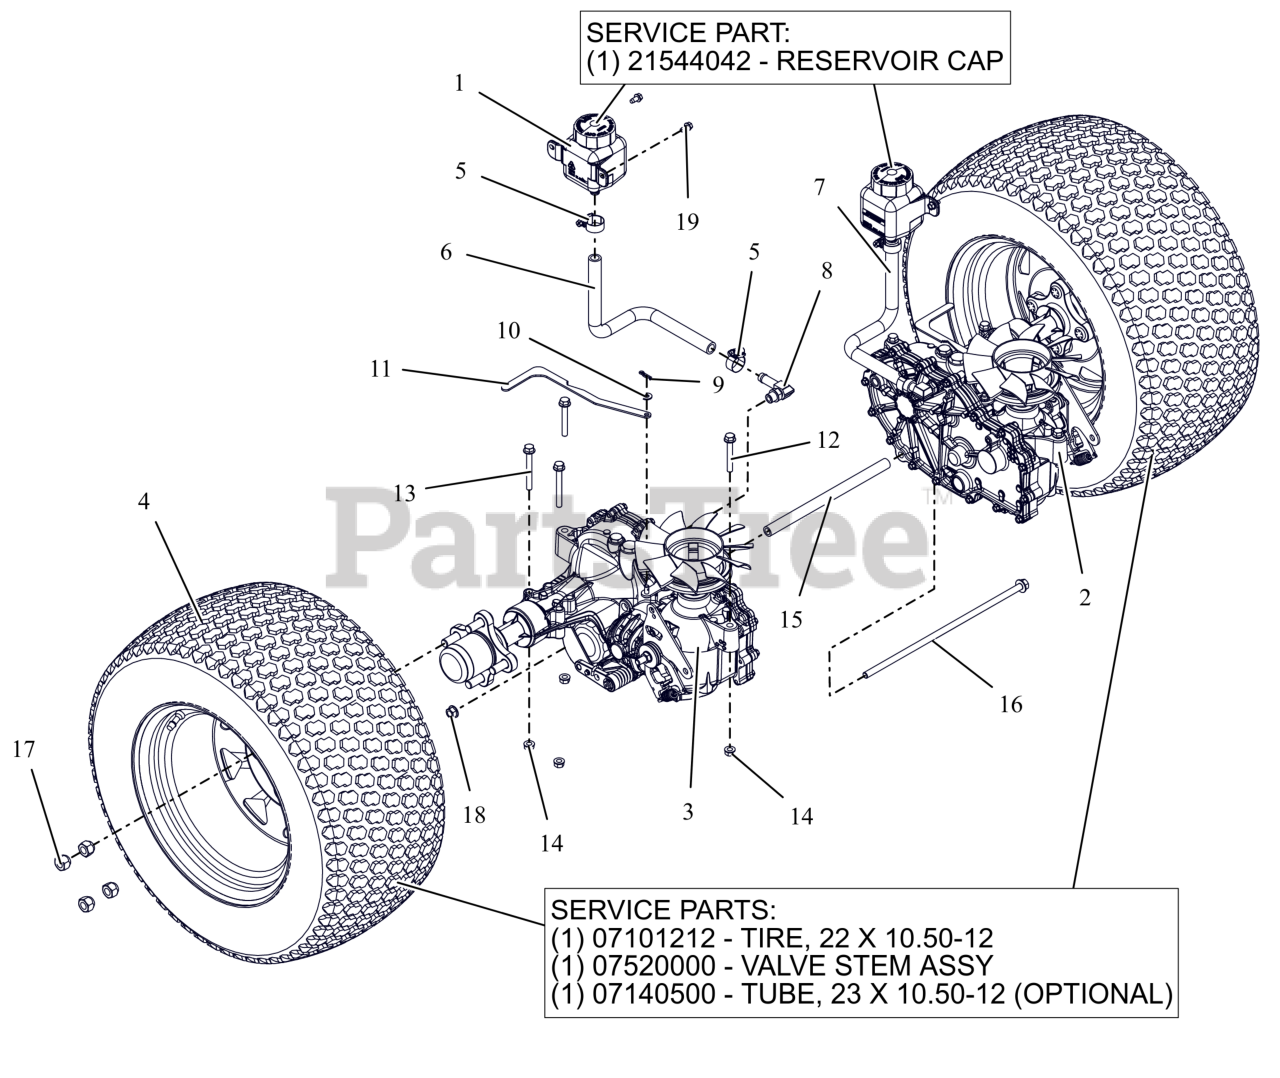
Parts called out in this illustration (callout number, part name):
1	TANK, EXPANSION
1	CAP, HYDRO RESERVOIR REPLAC.
2	TRANSAXLE, ZT3100 - LH
3	TRANSAXLE, ZT3100 - RH
4	ASM-WHL/TIRE 22X10.5-12 LG BLK
4	TIRE, 22X10.50-12
4	VALVE STEM ASS'Y
4	TIRE TUBE 22,23,24/8.50/9.50/10.00/10.50/12.00-12 4 PLY TR13 STRAIGHT VALVE
5	CLAMP,.88 DIA. HOSE
6	HOSE, FORMED EXPANSION -HD RH
7	HOSE, FORMED EXPANSION -HD LH
8	FITTING, HYD (90 DEG)
9	PIN, HAIR #225 .072X1.09
10	WSHR,FLT .281X.625X.065 ZCC
11	BRKT, VALVE DUMP
12	BLT,HEX-FLG .31-18X2.25 G5 ZCC
13	BLT,HEX-FLG .31-18X2.75 G5 ZCC
14	NUT,LK-CTR-FLG .31-18 GF ZCC
15	SPCR,TRANS. .406IDX.63ODX9.95L
16	BLT,HEX-FLG .38-16X13 G5 ZCC
17	NUT, WHEEL .50-20 ZCC
18	NUT-LK-TOP-FLG .38-16 ZC120
19	SCR-TAP .25-20X.50 HWH ZCC
